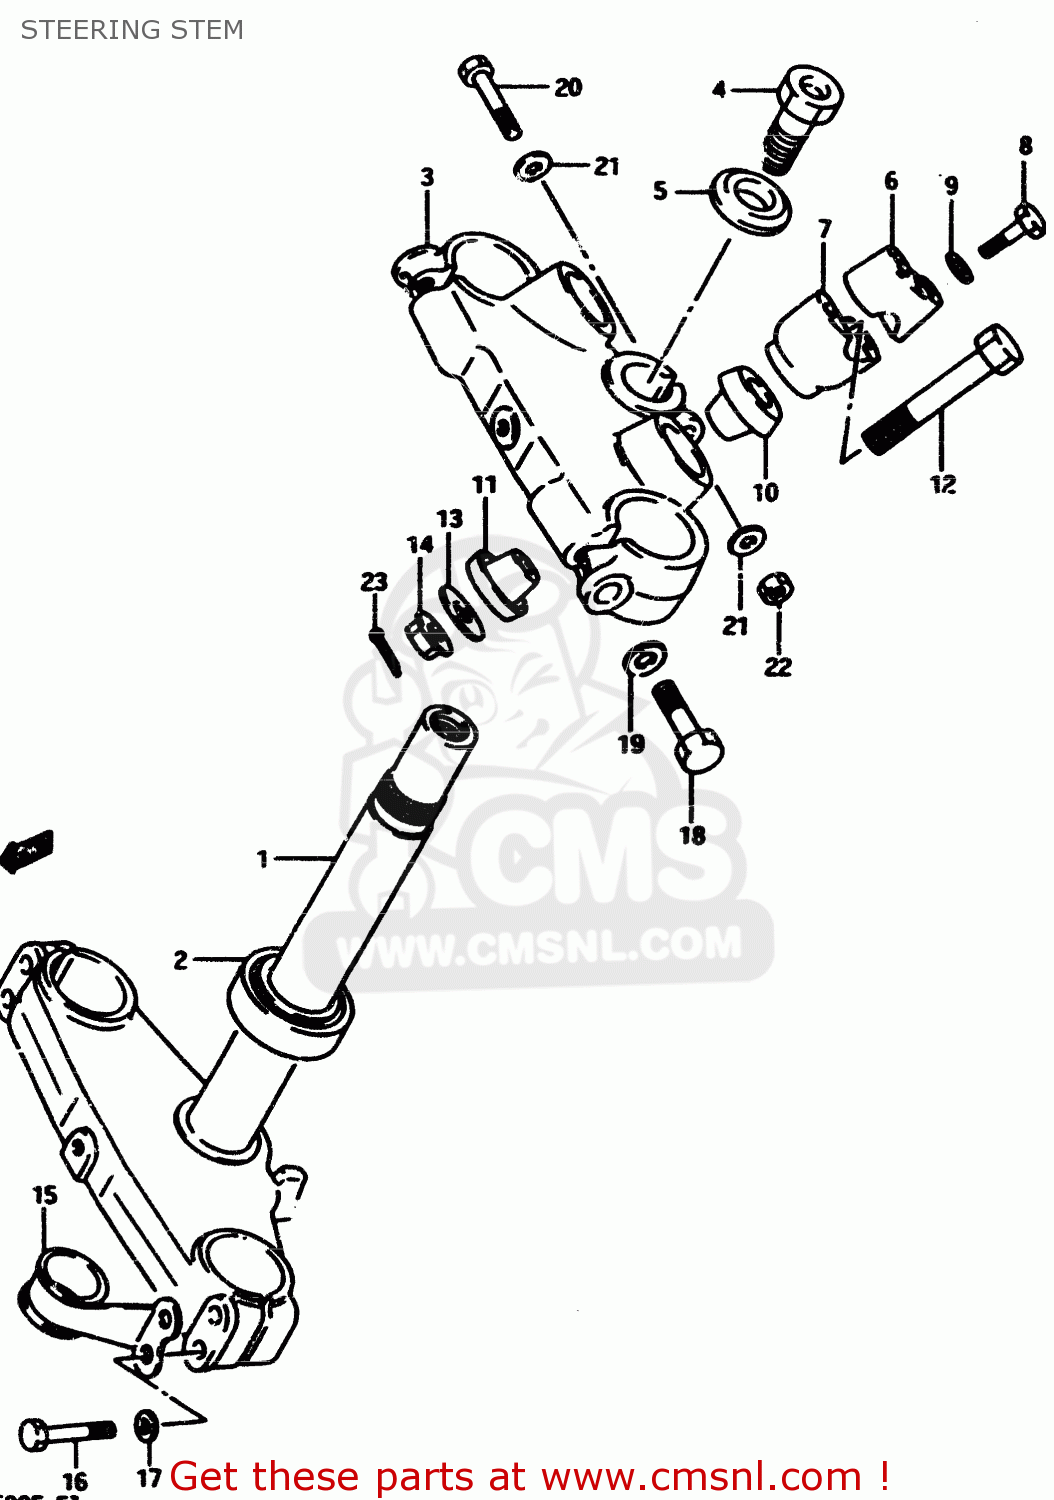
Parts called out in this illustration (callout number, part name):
1	STEM,STEERING
2	BEARING
3	HEAD,STEERING STEM
4	BOLT
5	WASHER
6	HOLDER,HANDLEBAR
7	HOLDER,HANDLE LWR
8	BOLT
9	LOCK WASHER
10	DAMPER,UPR
11	DAMPER,LWR
12	BOLT,HANDLE HOLDER
13	WASHER,HANDLEBAR HOLDER
14	NUT
15	GUIDE,CABLE
16	BOLT 8X40
17	WASHER,LOCK,8.
18	BOLT
19	LOCK WASHER
20	BOLT 8X50
21	WASHER
22	NUT
23	COTTER PIN
